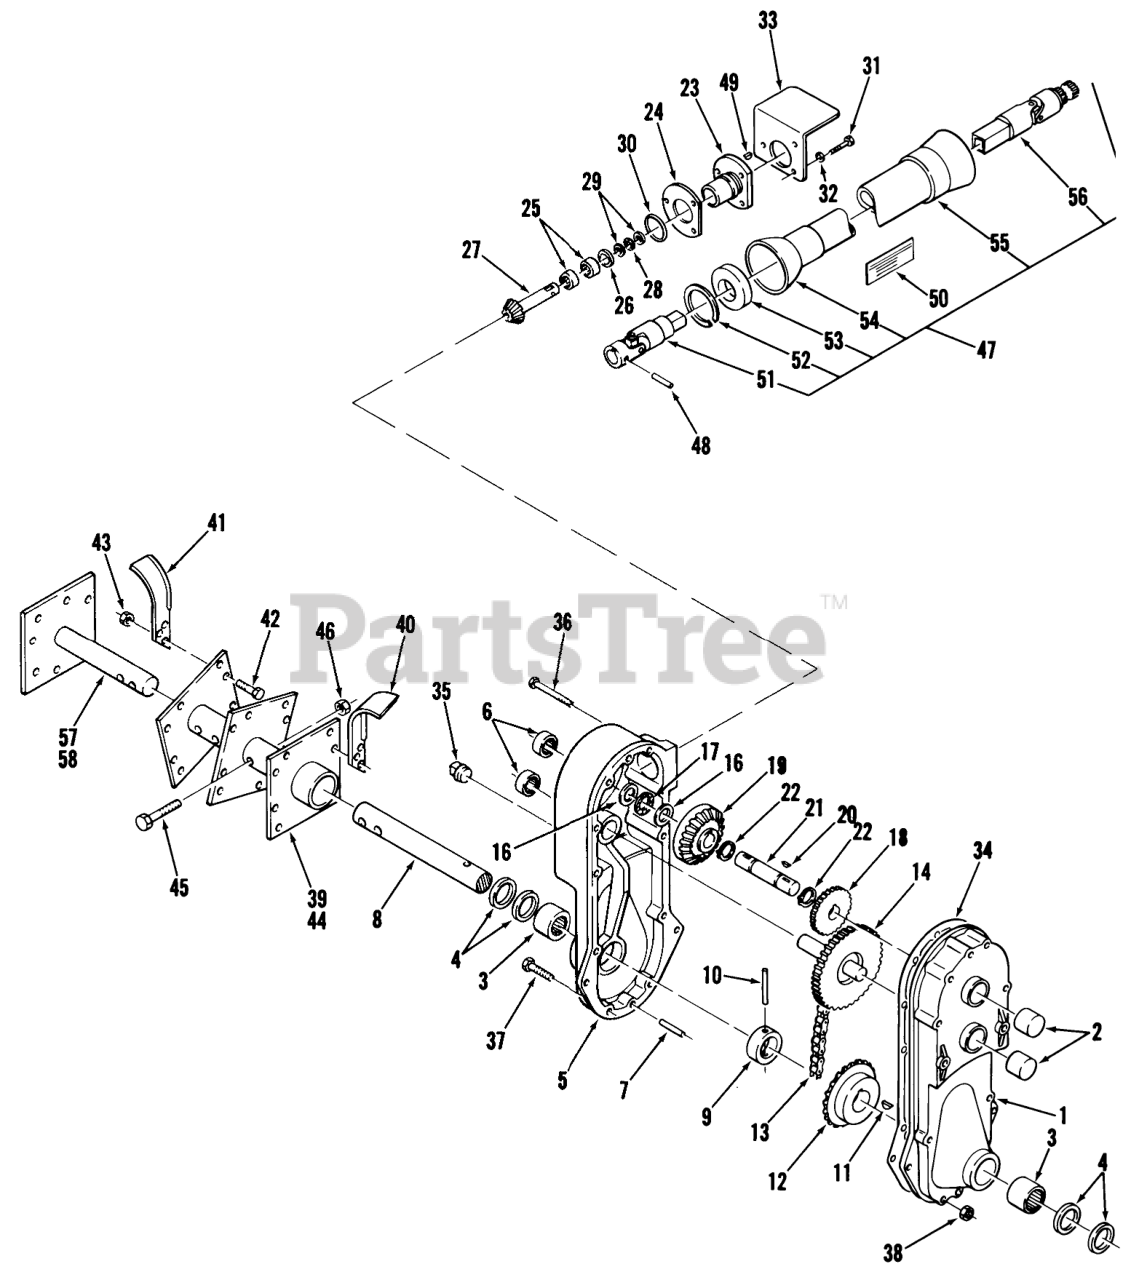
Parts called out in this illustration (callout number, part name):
1	Case-R.H.
2	BEARING-NEEDLE 1X1
3	Needle Bearing 11/2 x 1
4	SEAL-OIL
5	Case-L.H.
6	BEARING-NEEDLE
7	ROLL PIN 3/8 X 1
8	Tine Shaft 1 1/2 Dia.
9	Spacer
10	Spirol Pin 5/16 x 2 1/2
11	Key #129 Woodruff
12	Sprocket-20 T-#60
13	Chain #60-3/4 P x 44 P
14	GEAR ASSY
16	WASHER-THRUST
17	BEARING-THRUST
18	GEAR
19	Bevel Gear 40 T
20	KEY-WOODRUFF
21	SHAFT
22	Snap Ring
23	HOUSING-INPUT SHAFT
24	Gasket
25	BEARING-NEEDLE
26	SEAL-OIL
27	PINION&SHAFT
28	Bearing-Thrust
29	SHIM WASHER
30	O-RING
31	BOLT
32	LOCKWASHER
33	PTO Shield
34	GEAR CASE GASKET
35	SOLID PIPE PLUG
36	H H C S
37	Screw-Hex. Hd.
38	NUT
39	R.H. Tine Shaft Assembly
40	TINE RH R
41	TINE LH
42	7/16-14 x 1 1/4 Bolt
43	Nut
44	L.H. Tine Shaft Assembly
45	Bolt 5/8-11 x 2 3/4
46	E.S. Nut 5/8-11
47	Drive Shaft Assembly
48	SPIROL PIN
49	KEY-WOODRUFF
50	Washer
51	U-Joint with tube
52	Bearing Retainer
53	Bearing
54	ASSY SHIELD
55	Shield-2"
56	U-Joint with shaft
57	R.H. Tine Shaft Assembly
58	L.H. Tine Shaft Assembly
